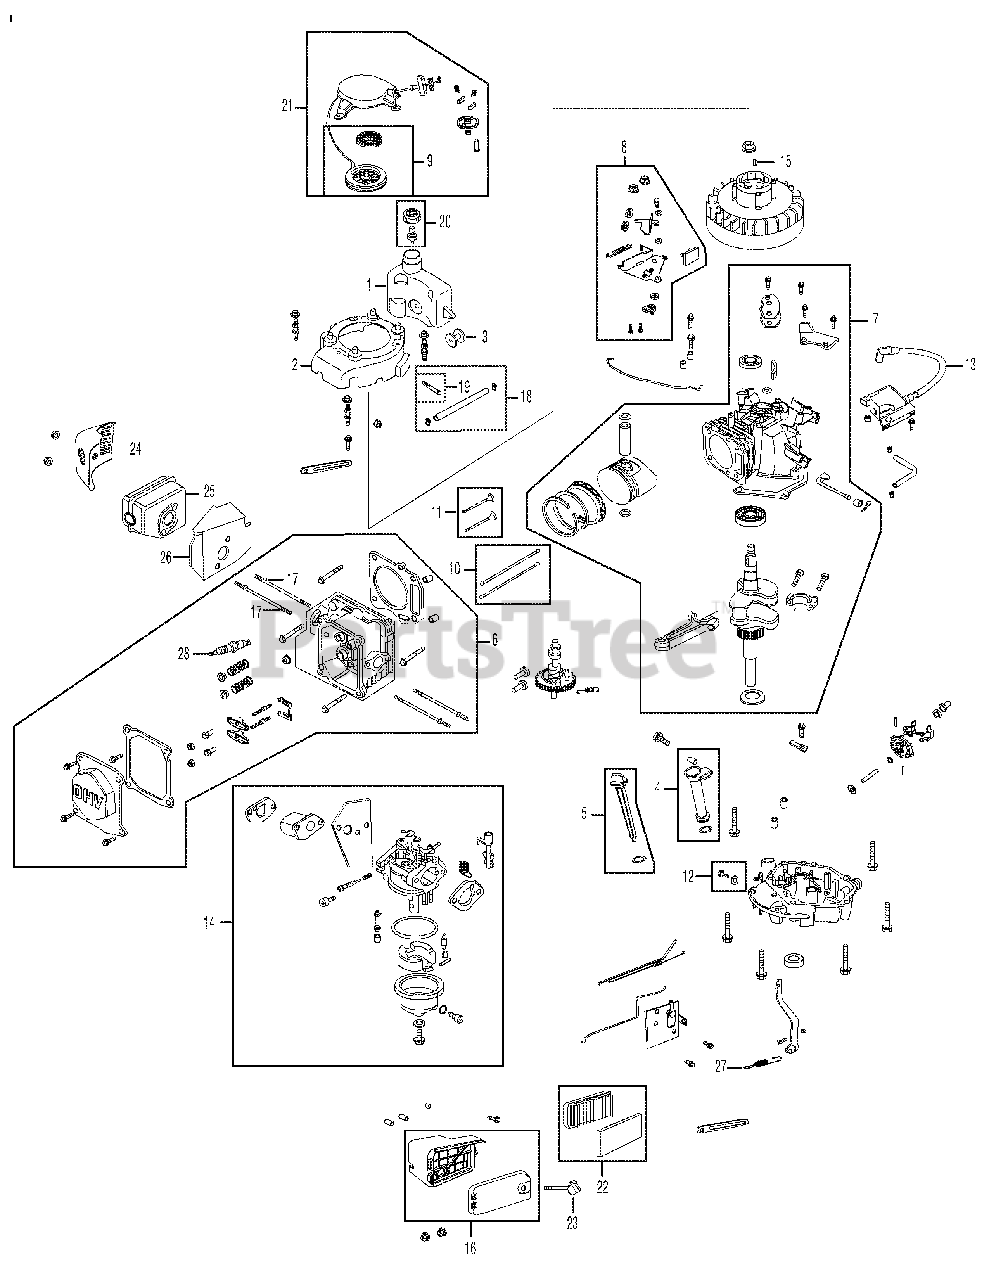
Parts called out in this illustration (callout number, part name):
1	Fuel Tank
2	Flywheel Shroud
3	Reed Valve Assembly
4	Oil Filler Tube Assembly
5	Dipstick Assembly
6	Cylinder Head Complete
7	Short Block Assembly
8	Stop Switch and Brake Assembly
9	Recoil Spring and Pulley Assembly
10	Push Rod Kit
11	Valve Kit
12	Oil Drain Plug and Washer Assembly
13	Ignition Coil
14	Carburetor Assembly
15	Flywheel Key
16	Air Cleaner Housing Assembly Complete
17	Muer Stud Assembly
18	Fuel Line Kit
19	Fuel Filter
20	Fuel Cap
21	Recoil Starter Assembly
22	Air Cleaner Kit
23	Air Cleaner Thumb Screw
24	Muffler Guard
25	Muffler
26	Muffler Gasket /Heat Shield
27	Governor Return Spring
28	Spark Plug
29	Roll Over Valve Assembly
30	Carbon Canister
31	Spark Arrestor
